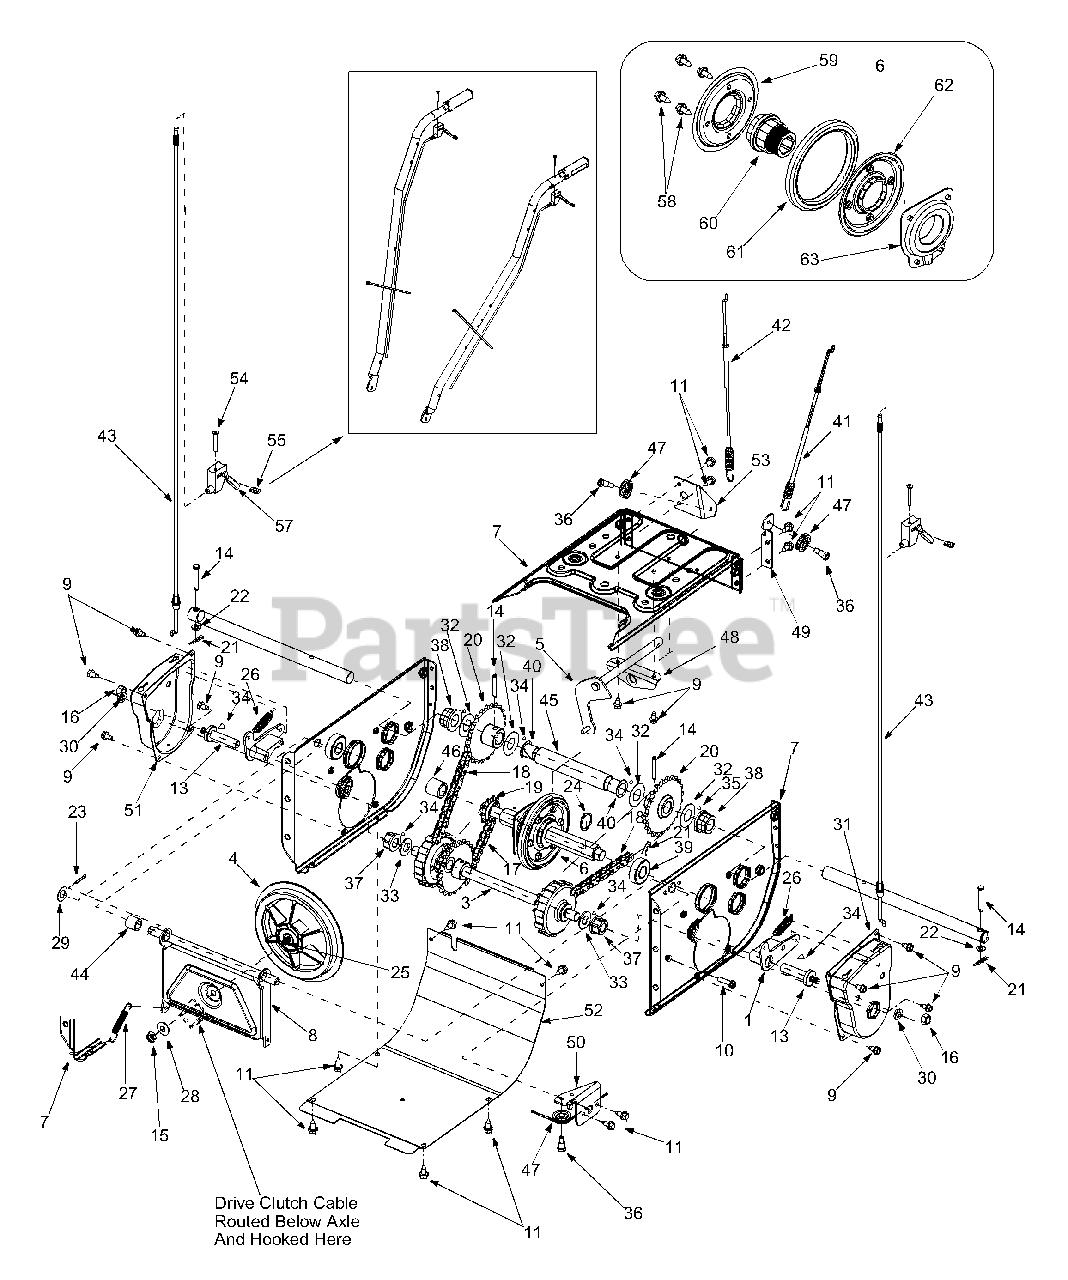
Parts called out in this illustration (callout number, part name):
1	Dogg Assembly: RH
3	Shift Assembly: Steerable Drive
4	Friction Wheel Disc Assy.
6	Bearing
10	Hex Washer Screw 1/4-20 x 1
11	Hex Screw 1/4-20 x .625"
13	Actuator Shaft
15	Jam Nut 3/8-24 Gr.8
16	Hex Nut: 3/8-16
17	Chain
18	Chain
19	Sprocket: 10T
20	Sprocket
21	Cotter Pin
22	Flat Washer
23	Cotter Pin
24	Snap Ring
25	Adhesive: Loctite
26	Extension Spring
27	Extension Spring
28	Bell Washer
29	Flat Washer
30	Lock Washer
33	Flat Washer
34	Lubricant: 6 in 1
35	Grease
36	Shoulder Screw
37	Hex Flange Bearing
38	Hex Flange Bearing
39	Ball Bearing
40	Flange Bushing
41	Auger Clutch Cable
42	Drive Clutch Cable
43	Steering Cable
44	Spacer
45	Axle Support Tube
46	Spacer
47	Roller Cable
55	Weld Nut
57	Turn Trigger
58	Hex Washer Screw 1/4-20
59	Friction Plate
60	Friction Wheel Hub
61	Friction Wheel Rubber
63	Friction Wheel Bearing
